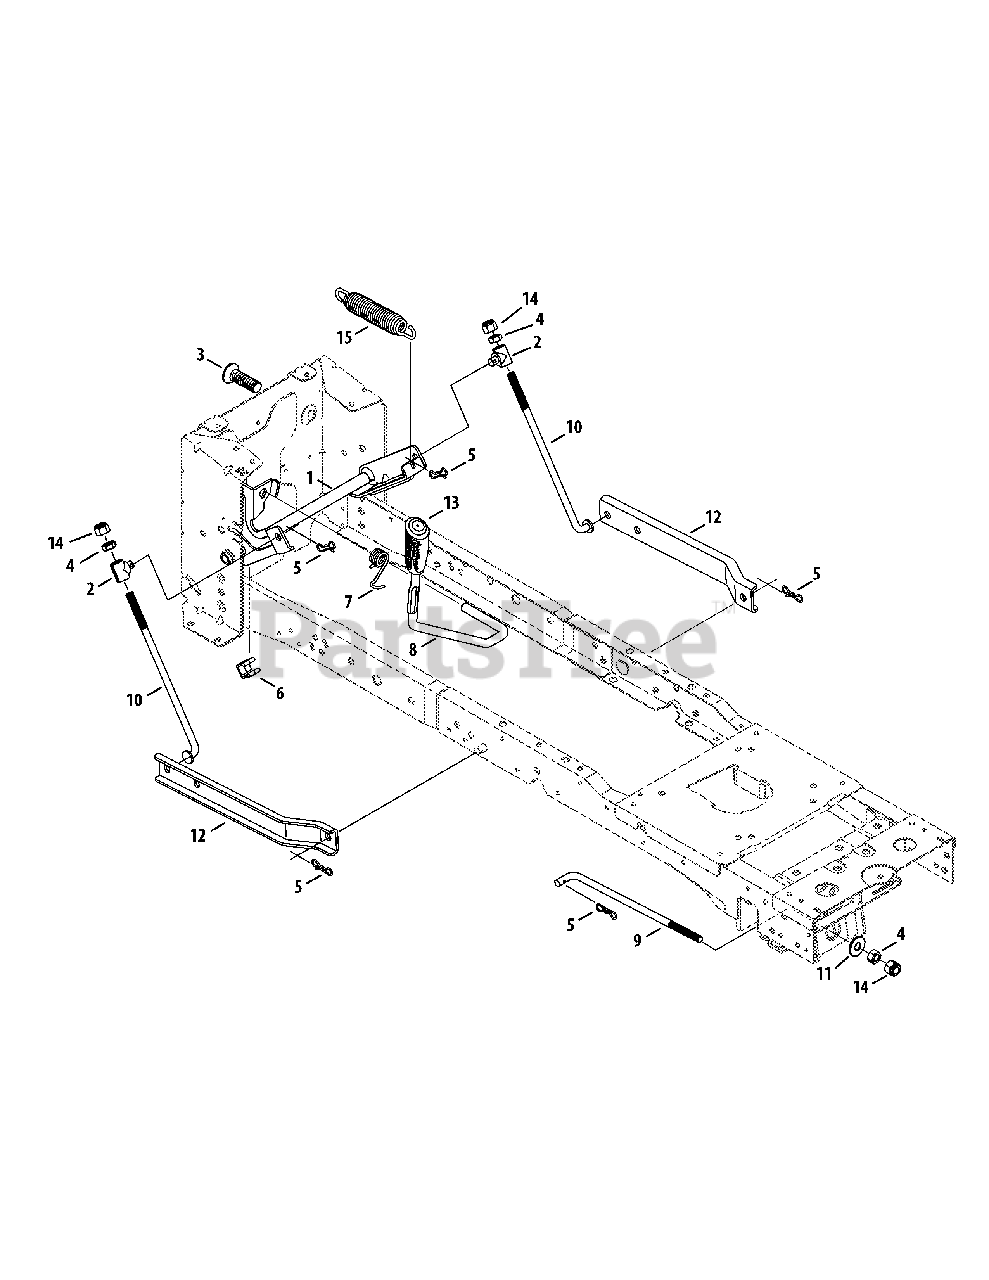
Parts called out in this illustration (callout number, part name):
1	Shaft Assembly, Lift
2	Ferrule, .510 x .496
3	Spring Insert
4	Nut, Jam, 1/2-13
5	Bow-Tie Cotter Pin
6	Spacer, .76 ID x .93 LG
7	Torsion Spring
8	Deck Lift Handle
9	Deck Lift Rod
10	Lift Adjustment Link
11	Pivot Cup
14	Hex Lock Nut, 1/2-13
15	Lift Assist Spring
